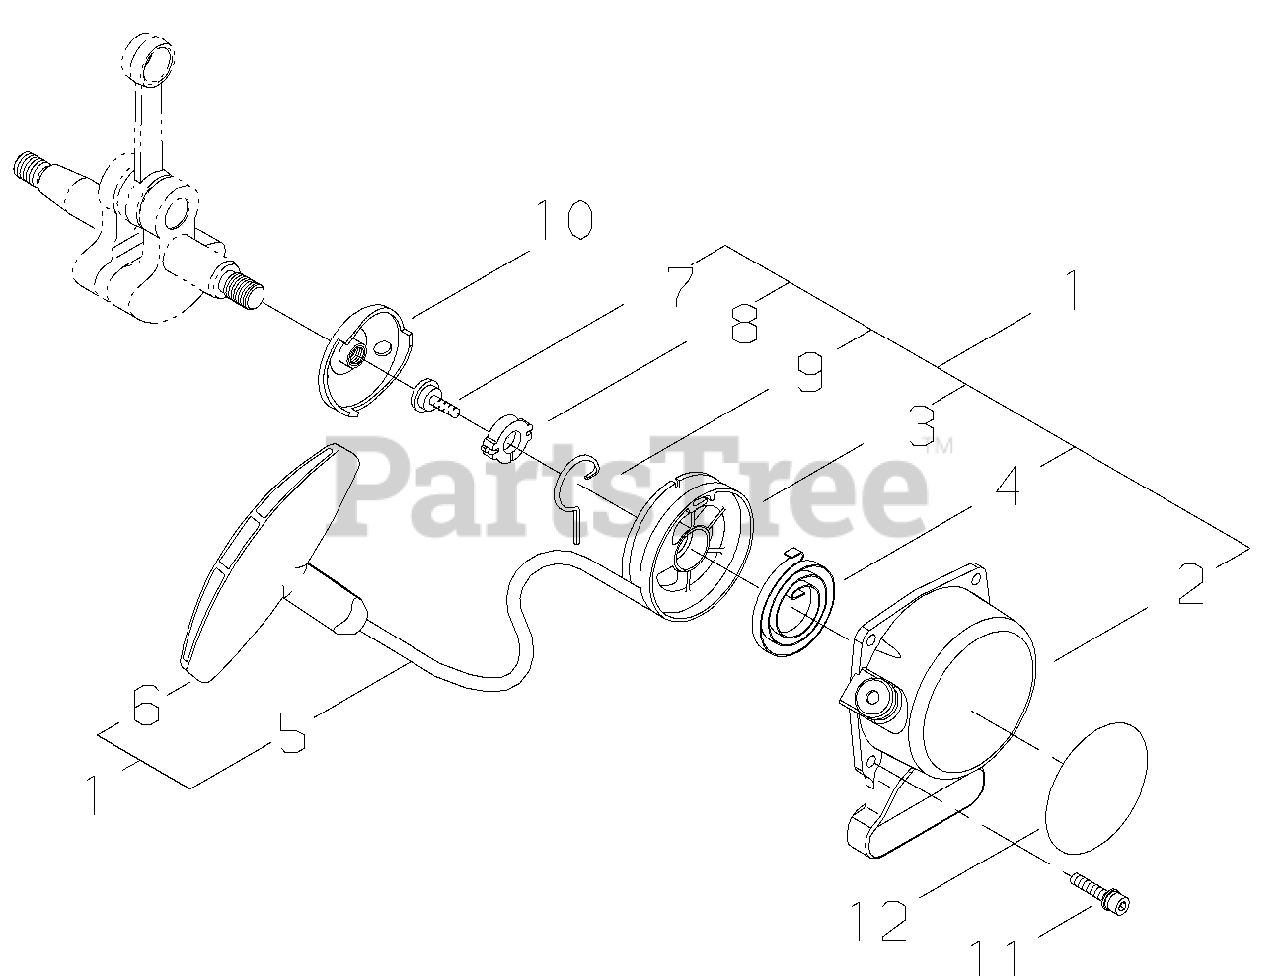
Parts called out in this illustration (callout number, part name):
2	CASE, STARTER
3	REEL, ROPE
4	SPRING, REWIND
5	ROPE, STARTER
6	GRIP, STARTER
7	SCREW - 5
8	WASHER - 5
9	CATCHER, PAWL
10	STARTER PAWL ASSY
11	SCREW - 4X14
12	LABEL - C4
